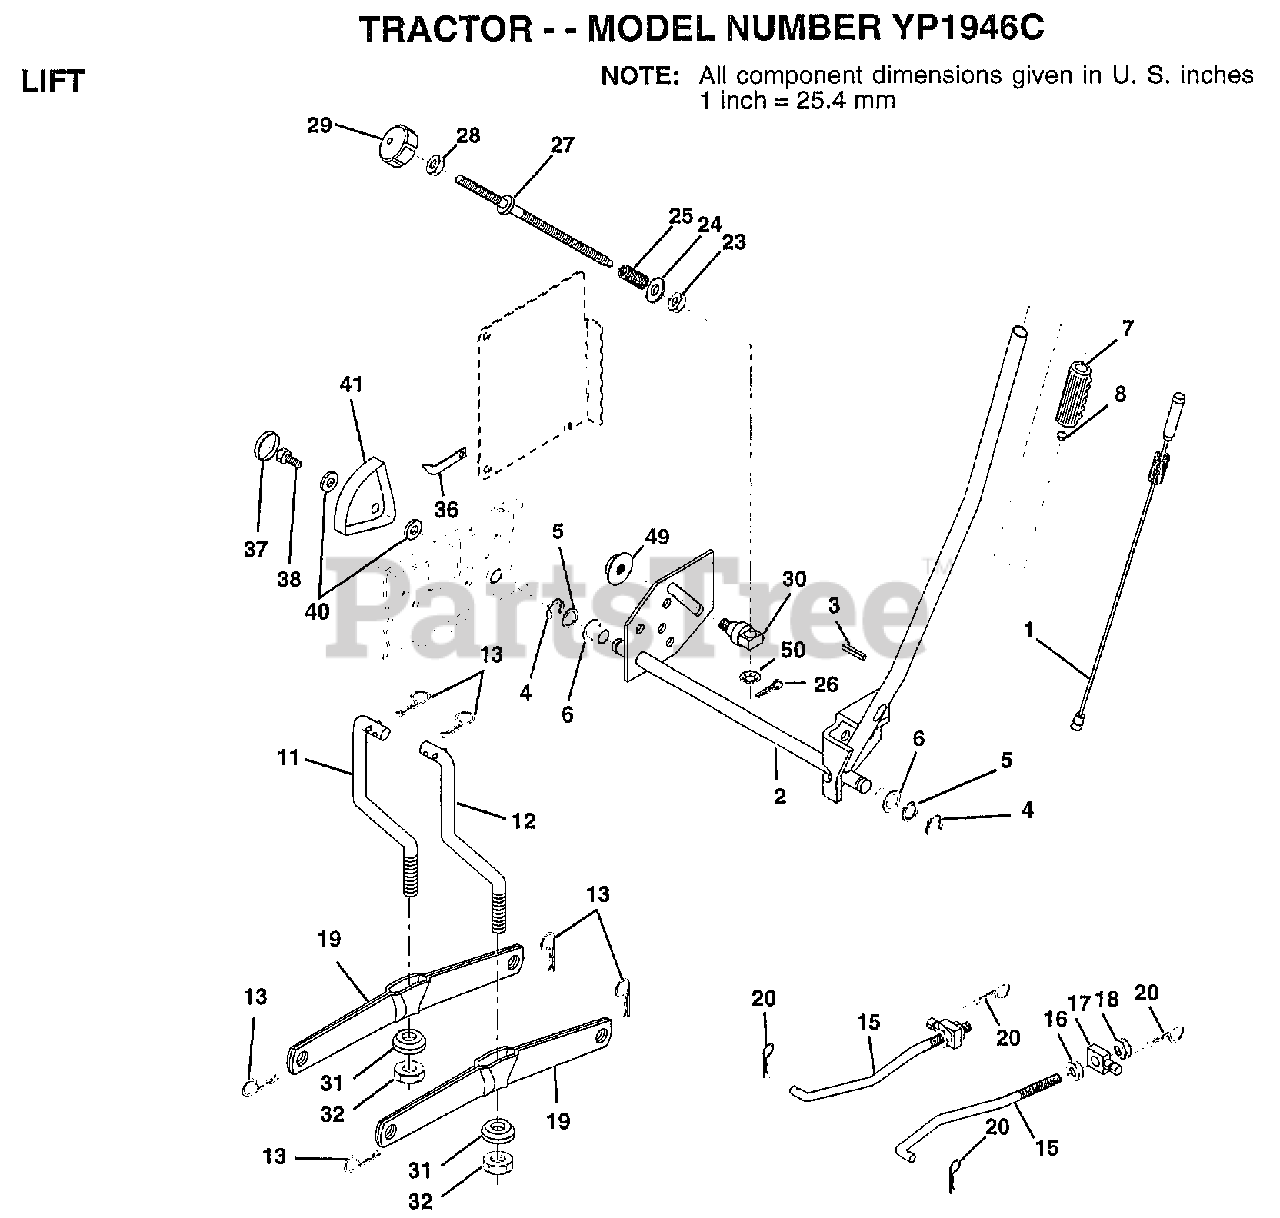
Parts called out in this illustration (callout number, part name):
1	WIRE ASM W.SPRING
2	"SHAFT ASM LIFT,RH"
3	PIN-GROOVE LT
5	WASHER
6	NYLON BEARING
7	GRIP HANDLE
15	LINK.FRONT
16	NUT
17	TRUNION
18	NUT.LK.W/WSH.1/2.
19	ARM SUSP REAR
20	RETAINER SPRING
23	NUT T
24	WASHER
25	SPRING T
28	NUT
29	KNOB INF 3/8-16
30	TRUNNION
31	BEARING PVT LH
32	NUT.CROWNLOCK.3/8
36	POINTER-INDICAT
37	"PLUG,HOLE"
38	SCREW
40	WASHER
41	HEIGHT INDICATOR
49	NUT.HXFLG.LOCK.
50	NUT PUSH M
